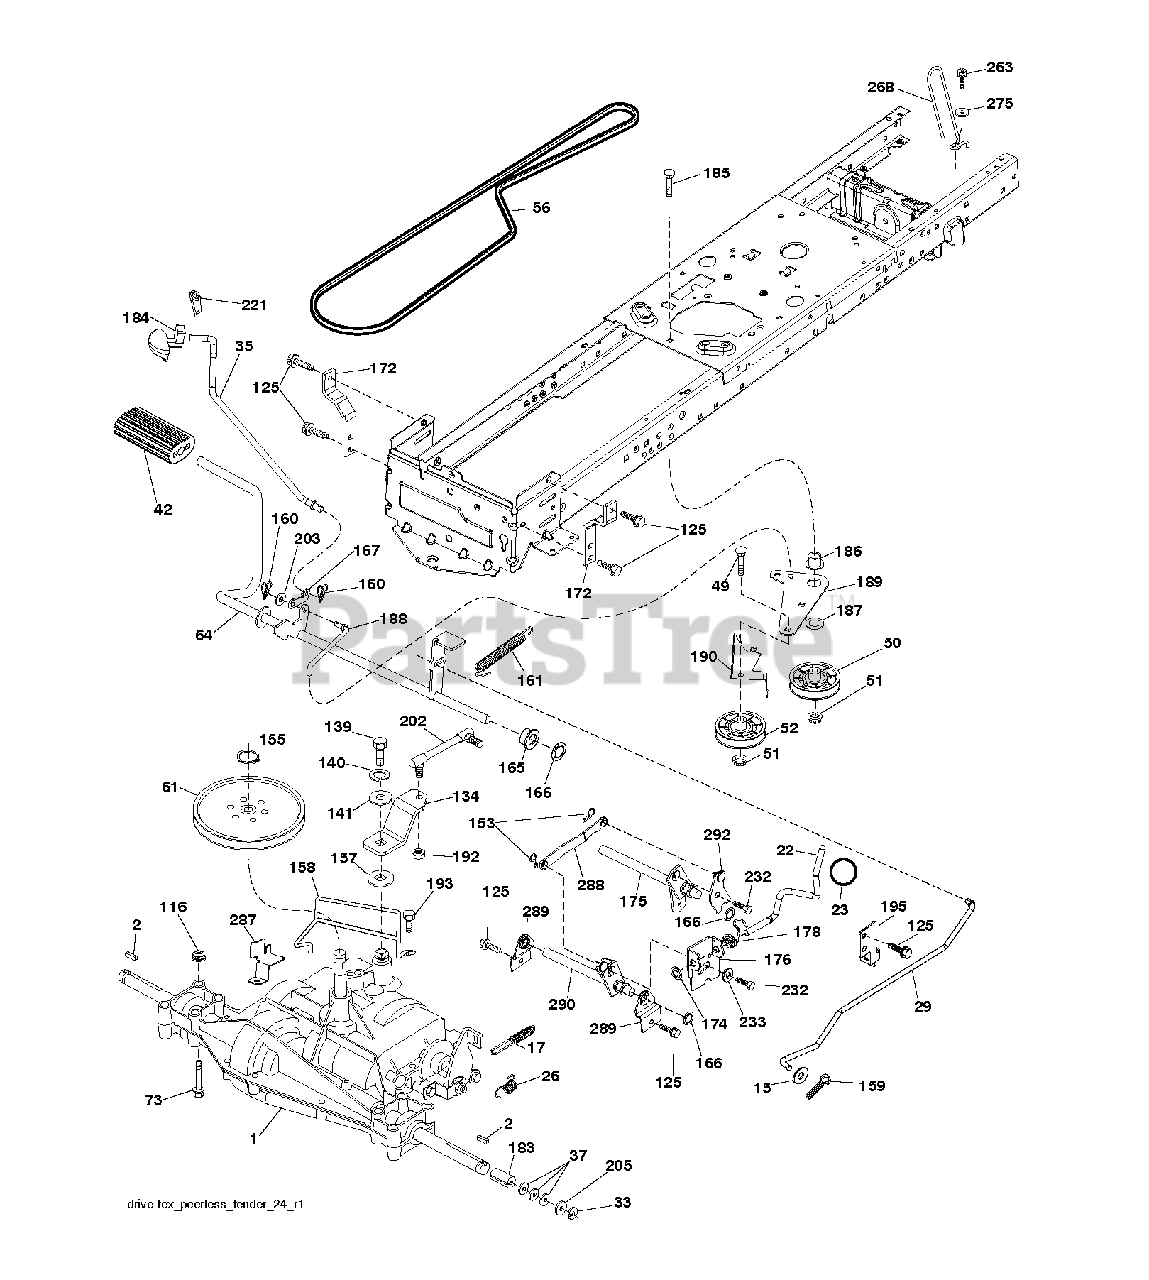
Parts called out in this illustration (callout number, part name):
17	SPRING.BRAKE.PEERLESS.TEX
22	SHIFTER.ASM.HANDLE.SRD
26	SPRING.BRAKE.RTN.GR.DR
29	ROD.BRAKE.PEERLESS
35	ROD.BRAKE.PARKING.LT.T
42	PEDAL COVER T
49	BOLT
50	IDLER.FLAT.910.OFFSET
51	NUT LOCK FLG 3/8-16 UNC
52	IDLER.V-GROOVE.910.OFFSET
56	BELT, V GROUND DRIVE 95 25
64	SHAFT.ASM.PEDAL.BRAKE.
116	NUT LOCK HEX FLANGE 5/16-18
125	SCREW
139	BOLT 1/4-28X3/4
140	LOCKWASHER
141	WASHER LT
153	RETAINER M
155	RETAINING RING LT
157	WASH-SHFT PLT LT
158	KEEPER.PMS.18/20.D4365
159	COTTER PIN
160	RETAINER CLIP
161	SPRING, RETURN LT
165	BUSHING.SHAFT.BRAKE.HAND
167	LATCH.BRAKE.SPRING
172	STRAP.TRQ.LH.GEAR.DRIV
174	NUT.PUSH.500.2006
175	SHAFT ASM SHIFT
176	ARM.CLEVIS.ROD.SHIFT
178	SPRING.TORSION.LIFT.HANDLE
184	HANDLE.PAKRING.BRAKE.
186	SPACER.RETAINER
187	WASHER 12/32X2X10GA
188	LINK.CLUTCH.GROUND.DRIVE
189	BELLCRANK.GROUND.DRIVE.TEX.
190	KEEPER.BELLCRANK.DRIVE
192	NUT LOCK CENTER 1/4 -28 FNTHD
193	SCREW 5/16"
195	BRKT.ROD.BRAKE.PEERLES
202	LINK.SHIFT.PMST.18"
203	WASHER
221	RETAINER.SPRING.CLIP.H
232	BOLT FIN HEX 7/16-14 X 1
233	WASHER SERRATED
263	SCREW, 3/8-16X3/4
275	WASHER
287	KEEPER.PULLEY.T/A.7.04
288	LINK.SHIFT.SLAVE.SRD
289	BRACKET.SUPPORT.SHIFT.OUTER
290	SHAFT.ASM.SHIFT.REAR.SRD
292	PLATE.ASM.SHIFT.FWD.SRD
